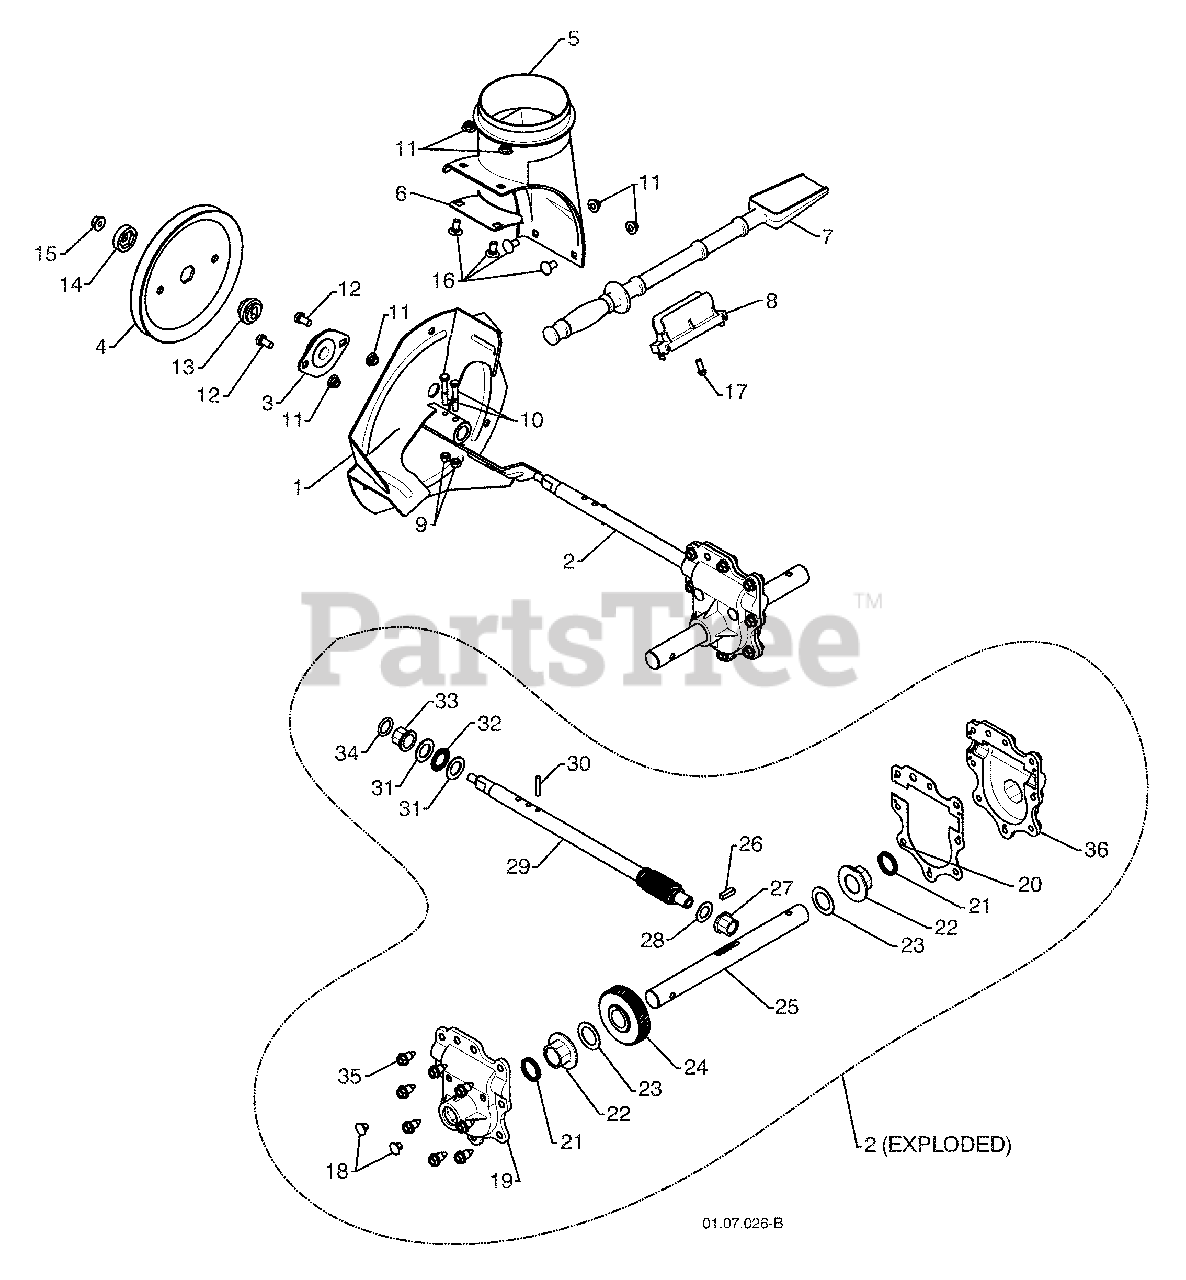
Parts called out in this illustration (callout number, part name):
1	IMPELLER
2	GEARBOX ASSEMBLY
4	IMPELLER PULLEY
5	DISCHARGE BASE
6	BRACKET CORNER
7	CLEAN OUT TOOL
9	NUT 1/4-20
10	SCREW 1/4-20 X .625
11	NUT 5/16-18
12	SCREW 5/16-18 X .625
13	IMPELLER HUB
14	IMPELLER SLEEVE
15	NUT 3/8-16
16	CARRIAGE BOLT
17	SCREW 13-16 X .625
18	PLUG
19	GEARBOX COVER RH
21	SEAL
22	BEARING
23	THRUST WASHER 1.00
24	WORM GEAR
25	AUGER SHAFT
26	SQUARE KEY
27	BEARING
28	THRUST WASHER
29	IMPELLER SHAFT
30	ROLL PIN
31	THRUST WASHER
32	THRUST BEARING
35	SCREW 5/16-18 X .750
36	GEARBOX COVER LH
